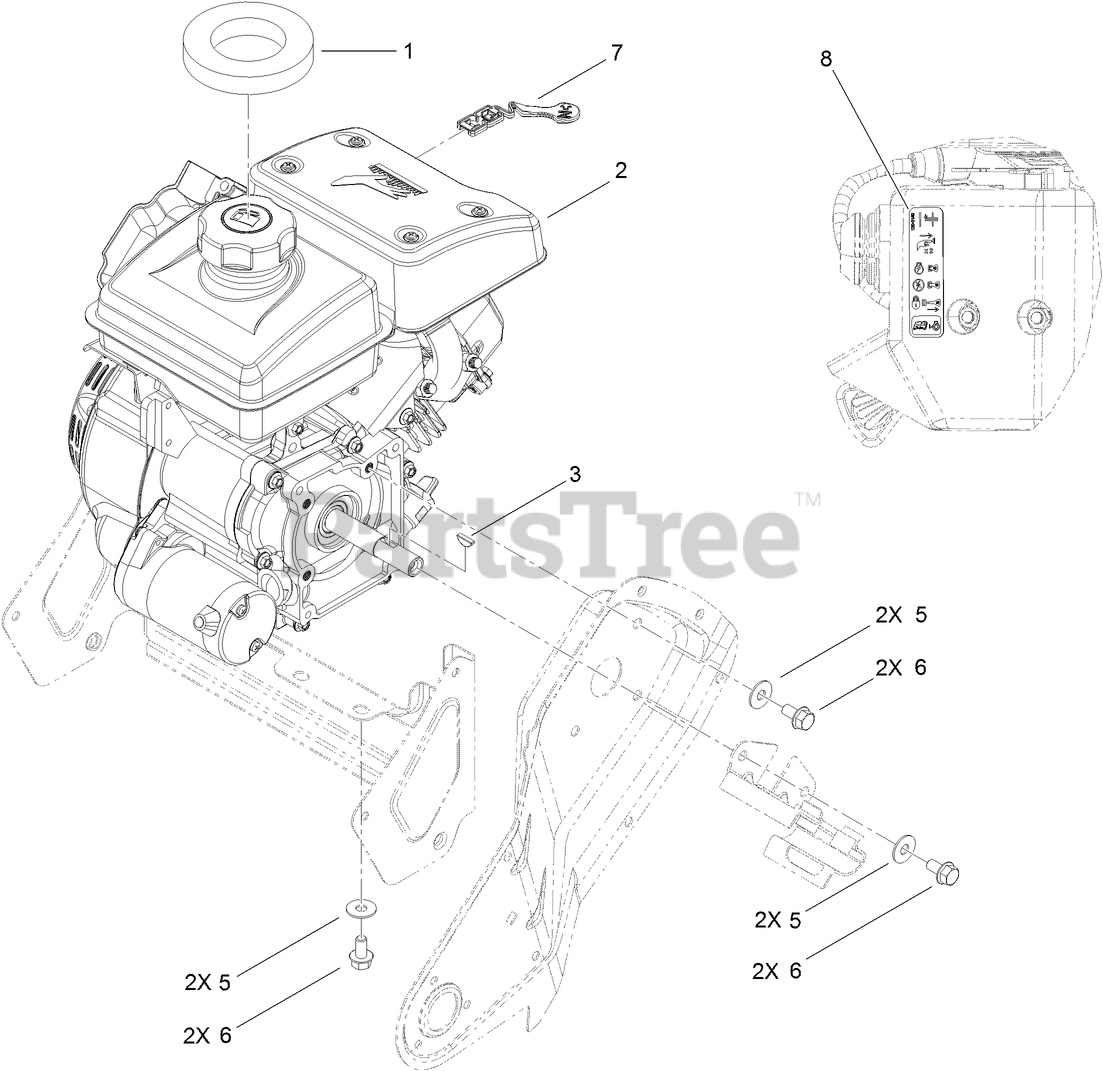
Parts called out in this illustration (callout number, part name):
1	SEAL-TANK
2	ENGINE-154FDS-1
3	KEY-WOODRUFF
5	WASHER-BELLEVILLE
6	SCREW-HHF
7	LEVER-CHOKE
8	DECAL-CONTROLS, ENGINE
